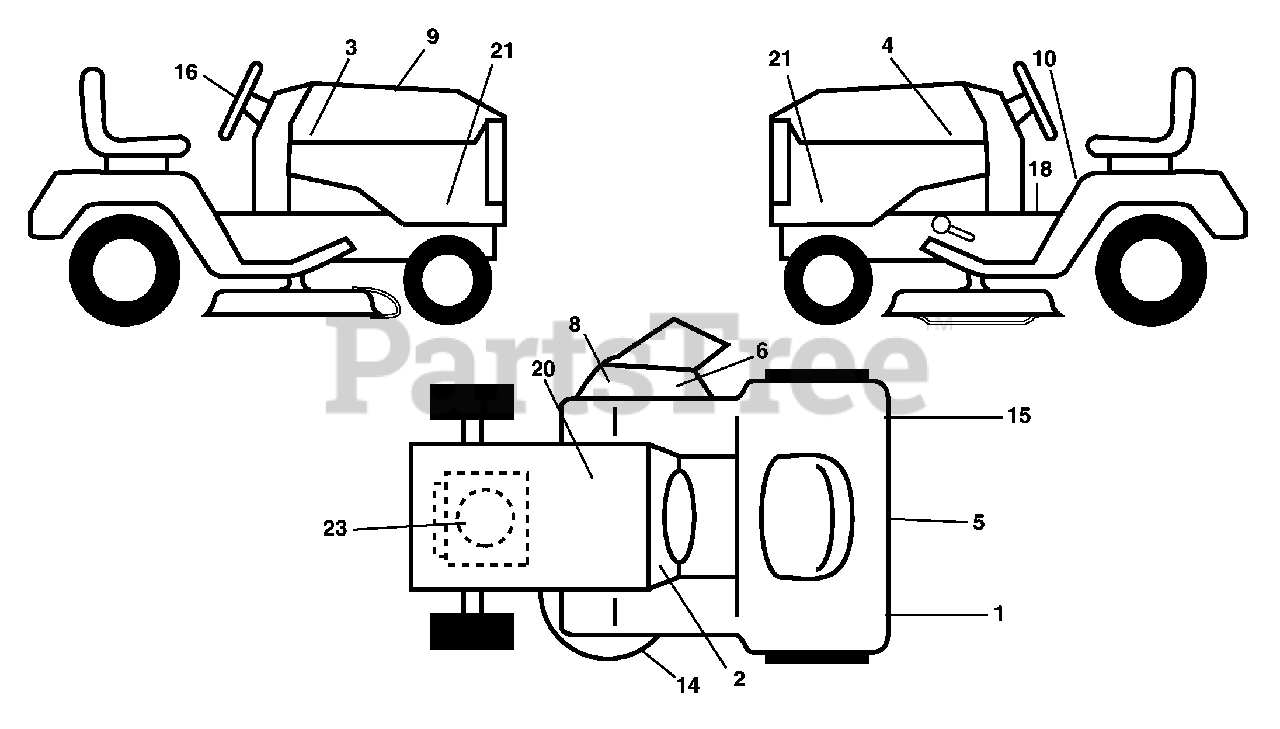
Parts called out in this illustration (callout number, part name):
1	Reflector, LH
2	Decal Dash
3	Decal Hood Rh
4	Decal Hood LH
5	Decal Fender Logo
6	Decal Warning, Keep Hand Away
8	Decal Deck "B" 42"
9	Decal Replacement Hood
10	Decal Fender Danger
14	Decal V-Belt Schematic
15	Decal Reflector, RH
16	Decal Ins Strg Whl
20	Decal Battery
21	Decal Side Panel Logo
23	Decal Engine
